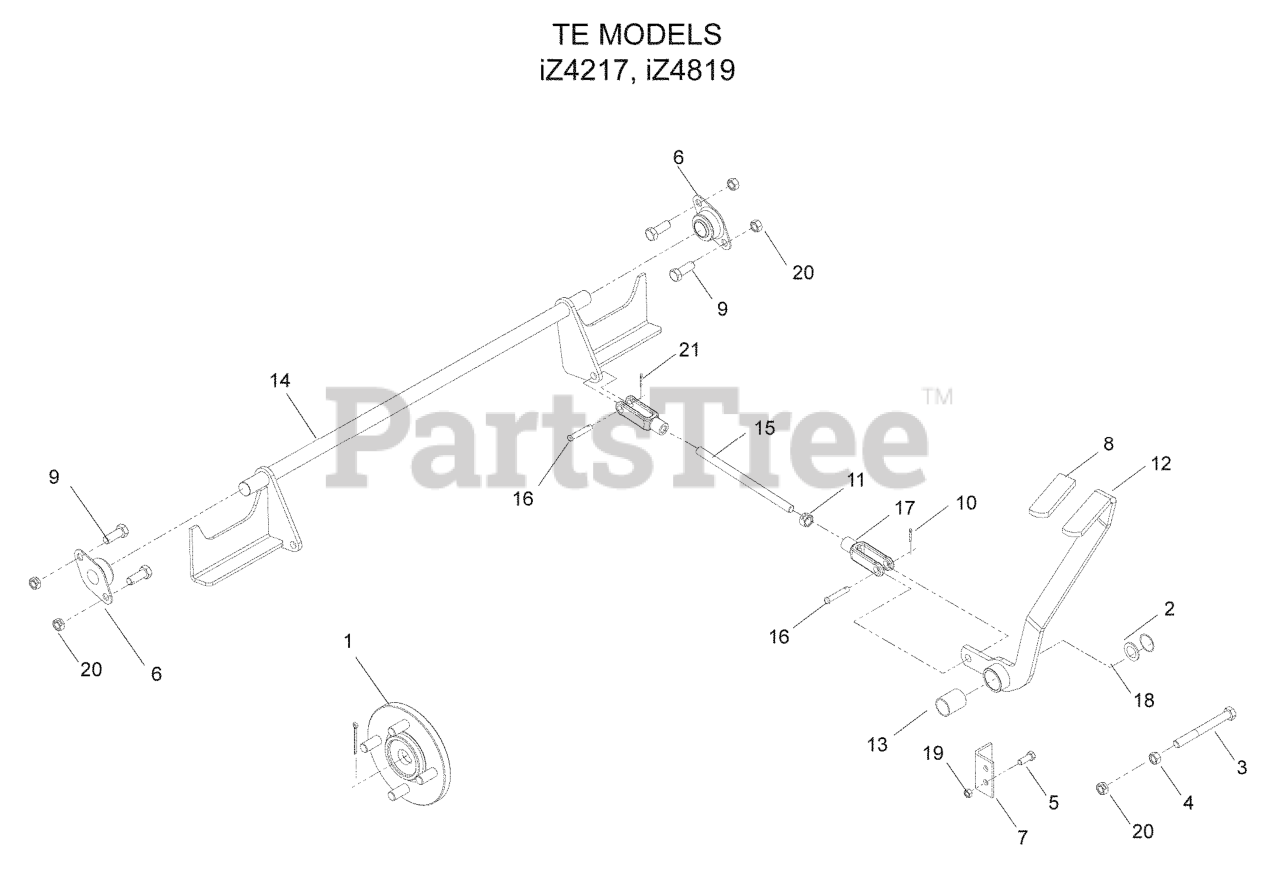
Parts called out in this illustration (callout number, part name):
1	HUB.WHEEL.ZTR
2	RETAINING RING, 7/8"
3	HCS 3/8C X 2 1/2
4	NUT 3/8C WHIZ
5	HCS 1/4C X 3/4 HCS
6	FLANGE BEARING
8	GRIP, PARK BRAKE
9	HCS 3/8-16X1.GRD.5.ZD
10	RP_COTTER PIN 1/8 X 3/4
12	BRAKE LEVER WLDMT
14	BRAKE SHAFT WLDMT
16	CLEVIS PIN 3/8 X 1 1/8
17	YOKE-3/8-24 PLTD
18	BSHG .875 X 1.375 X .074 ZD
19	NUT.1/4-20.HEX.NYLOC.ZD
20	NUT 3/8-16 NYLOC
